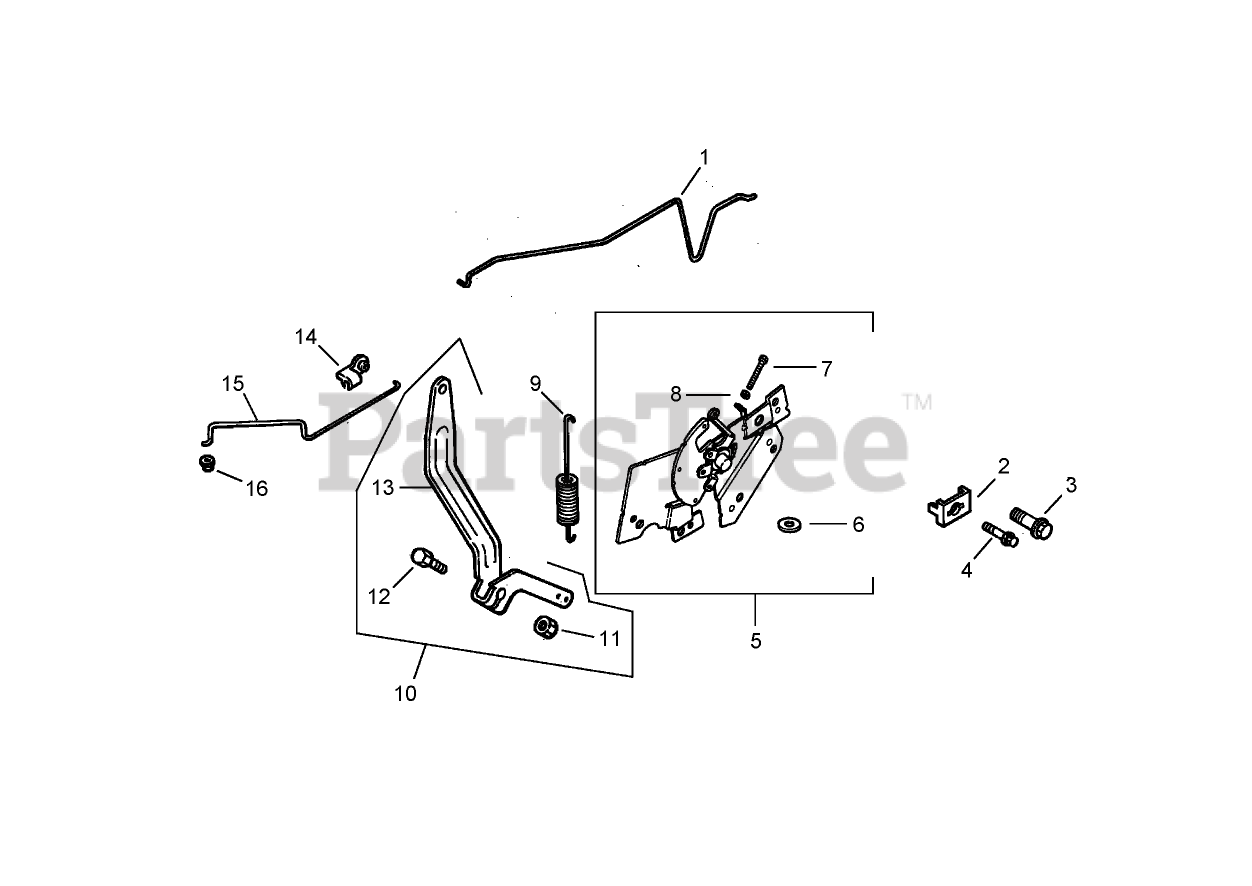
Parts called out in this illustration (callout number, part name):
1	Linkage-Choke
2	CLAMP-CABLE
3	SCREW-FLANGE, THREAD FORMING (M5X0.8X16)
4	Screw-Socket, 6 Lobed (Thread Forming, M6x1.0x20)
5	Speed Control ASM (Incl. Ref. No. 6-8)
6	Spacer-Shim
7	Screw (M4x0.7x30)
8	NUT (M4X0.7)
9	Spring-Governor
10	Governor Lever Kit (Incl. Ref. No. 11-13)
11	Nut-Flange, Hex (1/4-20)
12	Bolt-Square Neck, Round Head (1/4-20x1)
13	Lever-Governor
14	BUSHING-RETAINING, LINKAGE
15	Linkage-Throttle
16	BUSHING-LINKAGE, THROTTLE
